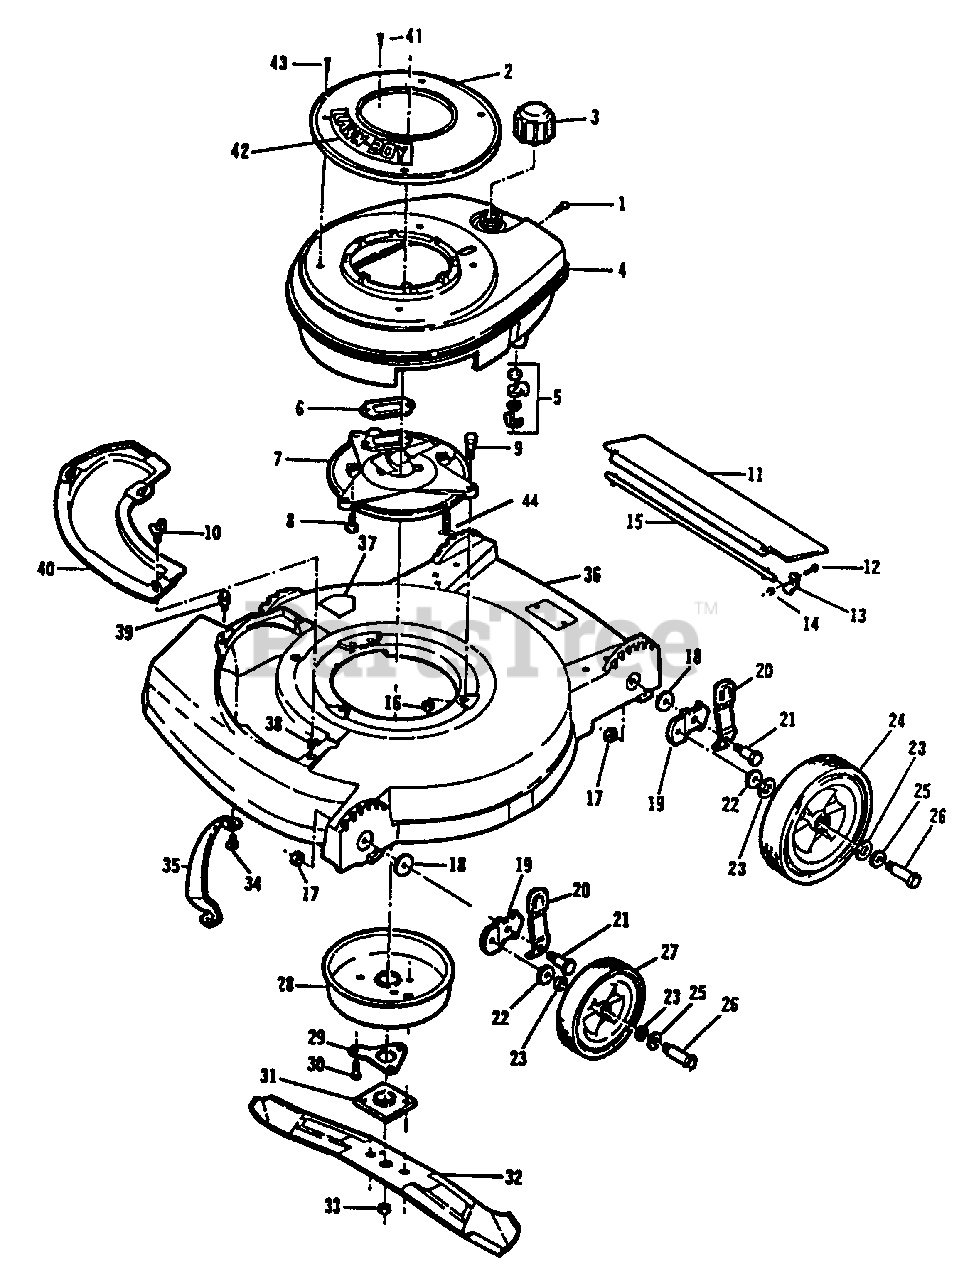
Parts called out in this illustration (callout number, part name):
1	Screw
2	Starter Base
3	Fuel Cap
4	Shroud-Engine
5	Fuel Shut-Off Assembly
6	Gasket-Exhaust
7	Plate-Muffler
8	Screw-Muffler Plt. to Block
9	Screw-Muffler Plt. to Hsg.
10	Wing Screw
11	Shield-Trailing
12	Screw-Trailing Shield
13	Clamp
14	Nut
15	Rod-Trailing Shield
16	Nut-Muffler Plt. to Hsg.
17	Nut-Wheel Ht. Adjust
18	Washer-Wheel Ht. Adjust
19	Bracket-Wheel Ht. Adjust
20	Knob and Spring Assembly
21	Bolt-Shoulder
22	Washer
23	Washer-Felt
24	Wheel-Rear
25	Washer-Wheel Bolt
26	Bolt-Wheel
27	Wheel-Front
28	Muffler Cover Assembly
29	Support-Crankshaft
30	Screw-Muff. to Muff. Plate
31	Collar and Plate Assembly
32	Blade 19"
33	Nut
34	Screw
35	Toe Bar
36	Housing Assembly
37	Decal-Blade Contact Warning
38	Grommet
39	Screw-Plate Mounting
40	Cover Plate
41	Screw-Starter Mounting
42	Applique
43	Screw-Shroud
44	Screw-Muffler Plt. To Block
